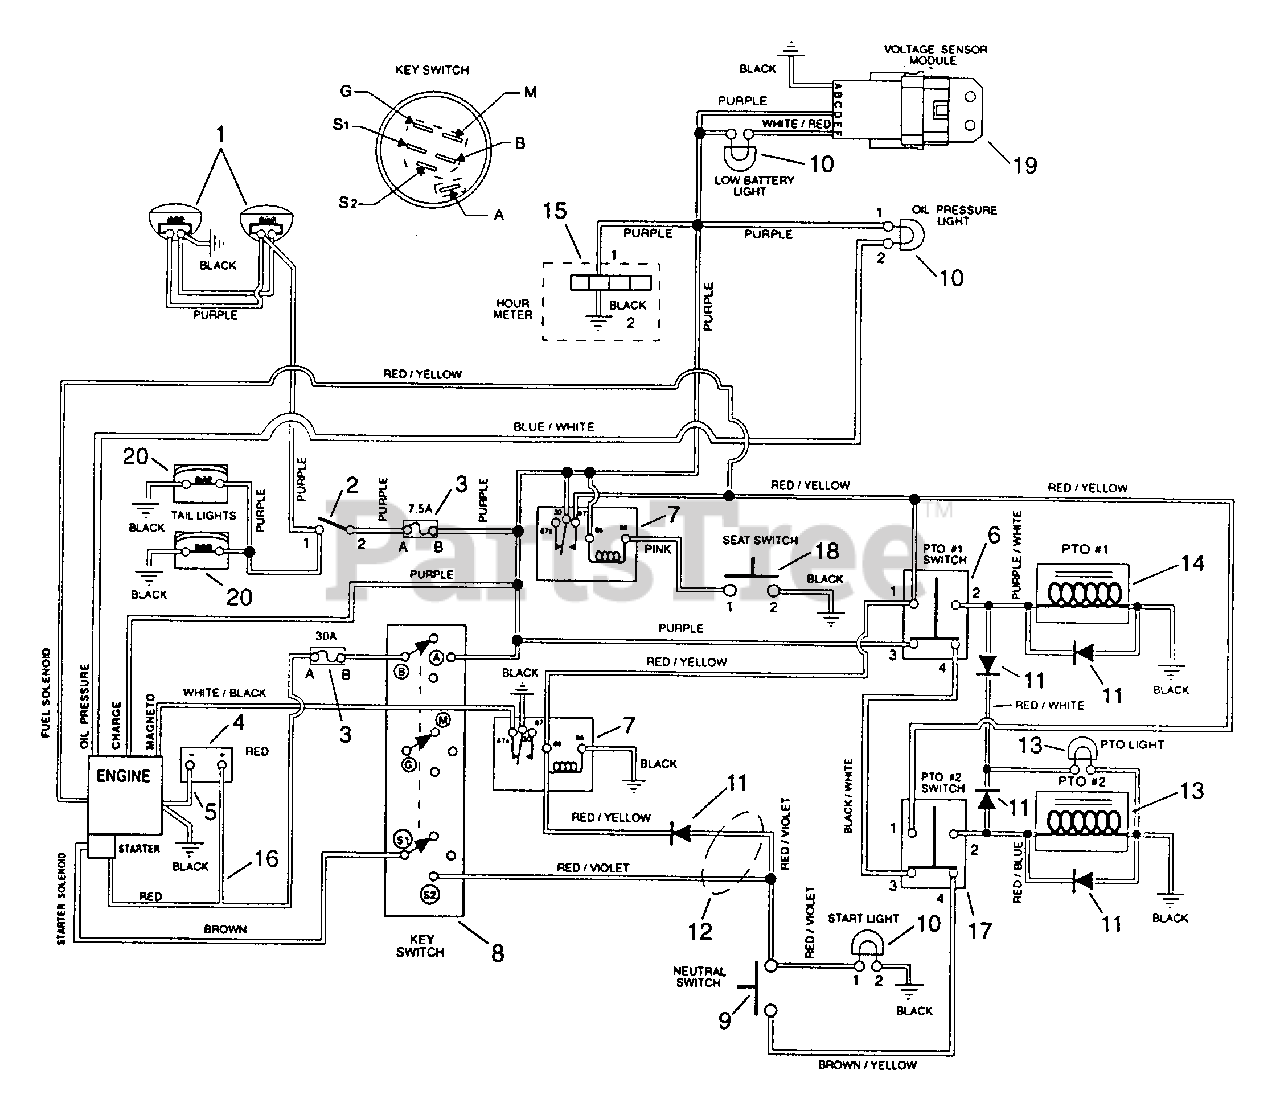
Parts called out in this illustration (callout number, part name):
1	HEADLIGHT- RH
1	HEADLIGHT- LH
2	SWITCH - LIGHT
3	7.5 AMP Fuse
3	30 AMP Fuse
4	BATTERY
5	CBL,NEGATIVE BATTERY 20.00
6	PTO KNOB/ SWITCH ASSY
7	RELAY
8	KEY SWITCH
9	SWITCH- SINGLE POLE N.O.
10	#194 Bulb
11	MOLDED DIODE PLUG 1 AMP
12	WIRE HARNESS - KOHLER V TWIN
13	ELECTRIC CLUTCH
14	CLUTCH-ELEC. WARNER I-5215-62B
15	HOUR METER
16	CBL,BATTERY TO SOLENOID
17	CLUTCH SWITCH
18	SWITCH- SEAT
19	MODULE - VOLTAGE SENSOR
20	TAIL LIGHT ASSEMBLY W/BULLET
